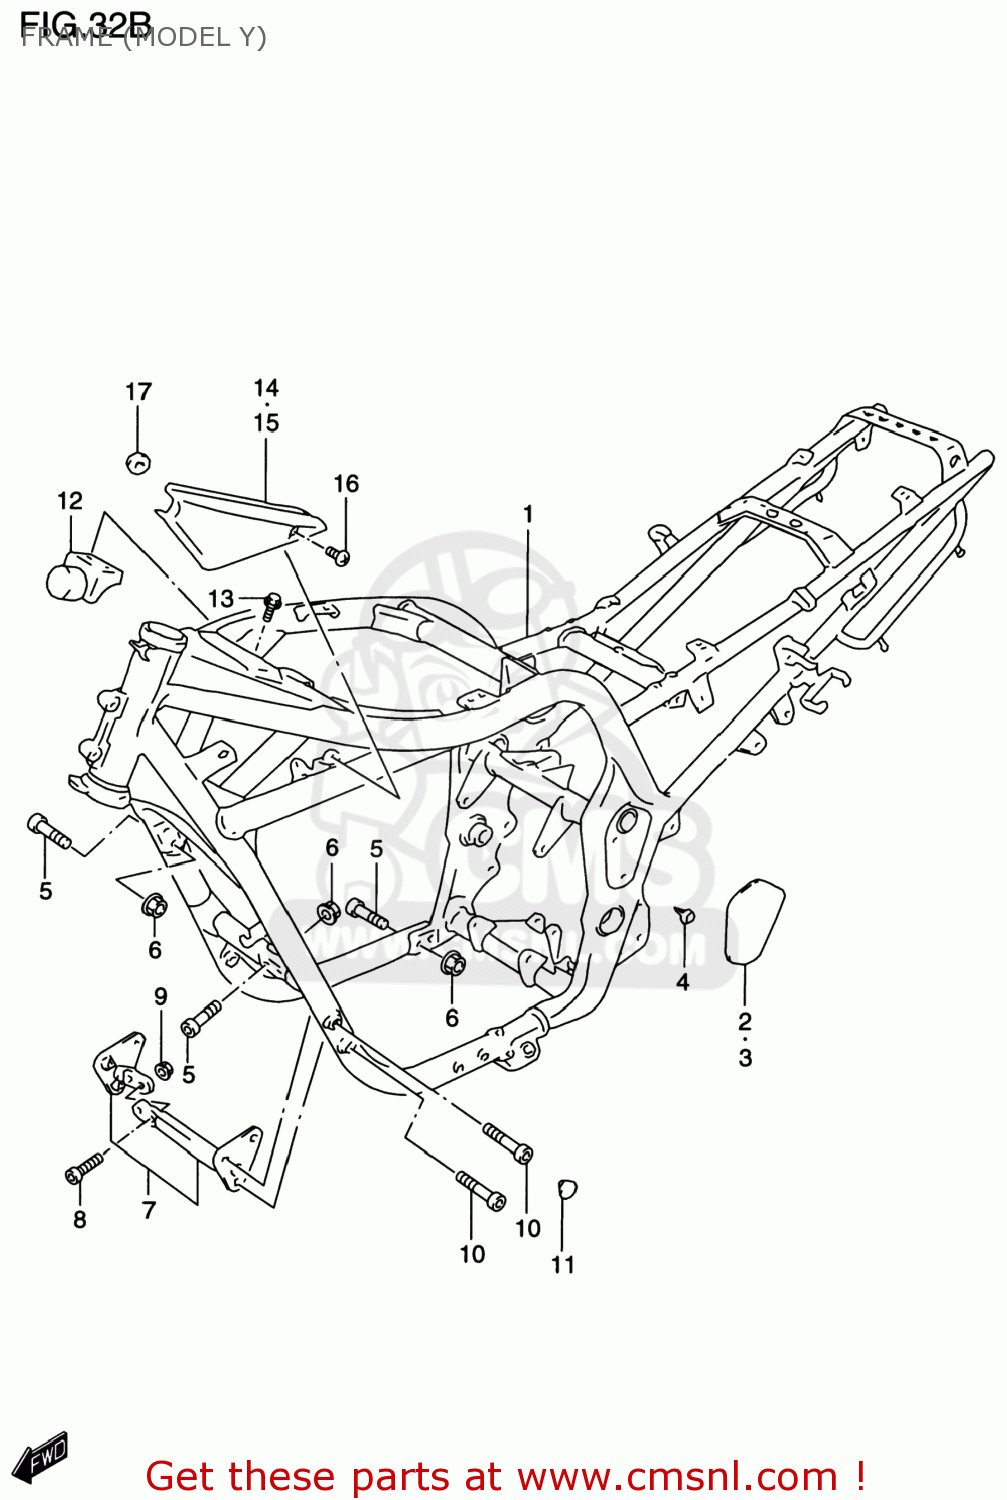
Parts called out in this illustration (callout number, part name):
1	FRAME(MAROON)
2	COVER,FRAME BODY,R
3	COVER,FRAME BODY,L
4	CLIP
5	BOLT(10X33)
6	NUT
7	PLATE,ENGINE MOUNT NO.1
8	BOLT
9	NUT
10	BOLT
11	CAP(OD:12)
12	DAMPER COMP,FRAME
13	BOLT
14	COVER,FRAME HEAD,R
15	COVER,FRAME HEAD,L
16	SCREW(5X12)
17	CUSHION
